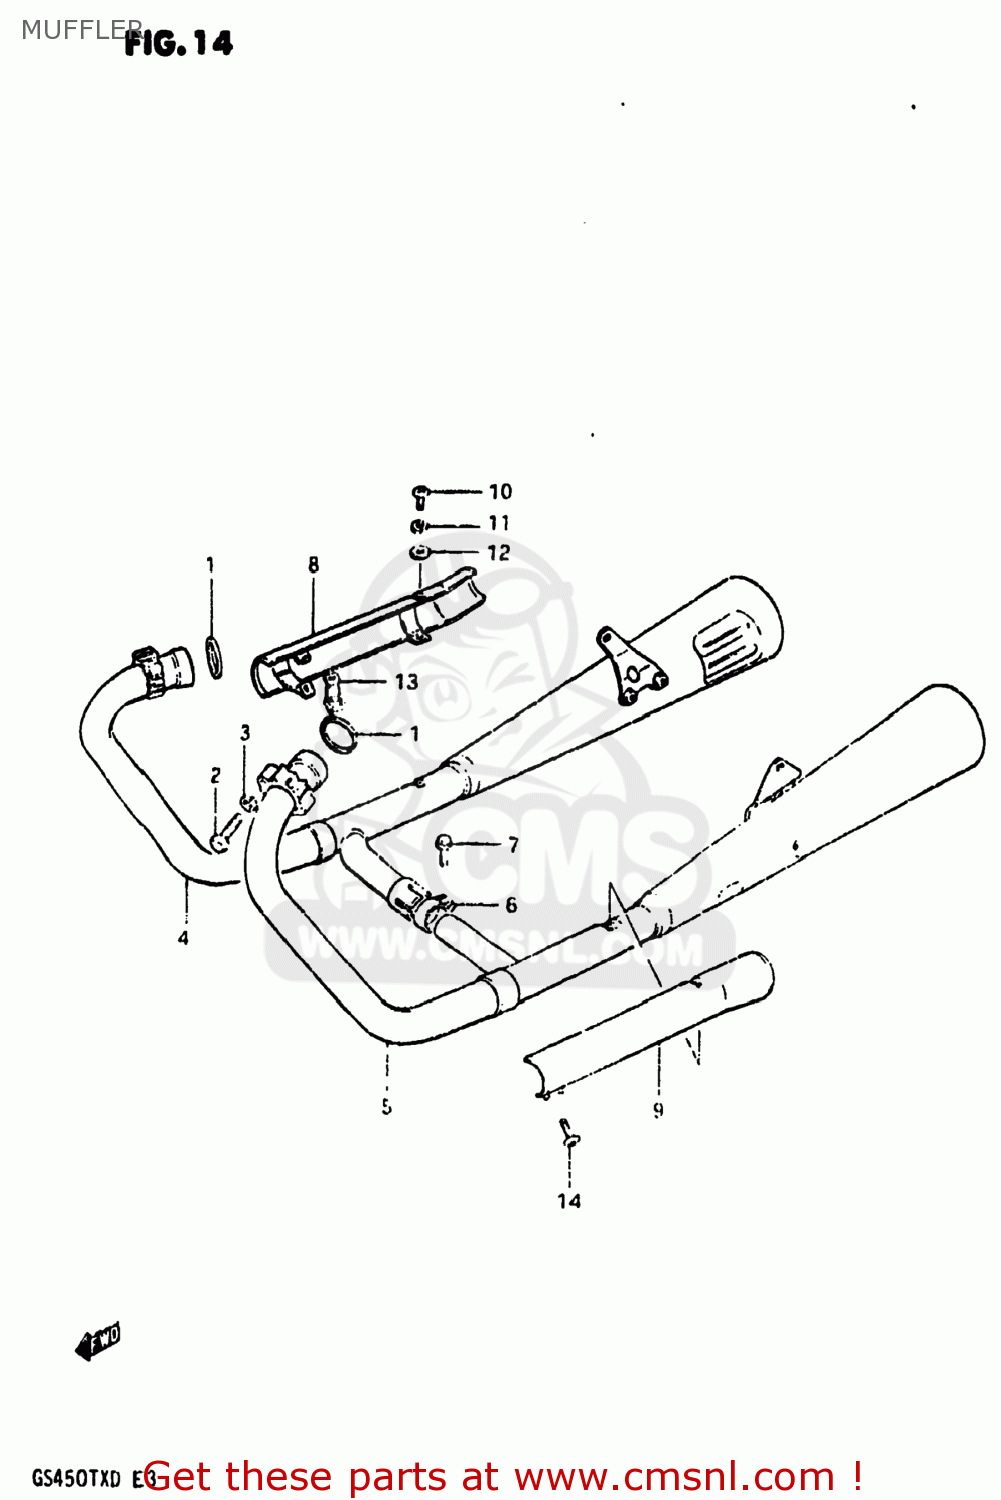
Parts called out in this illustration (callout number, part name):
1	GASKET,EXHAUST PIPE (NAS)
2	BOLT 8X40
3	LOCK WASHER
4	MUFFLER ASSEMBLY
5	MUFFLER ASSEMBLY
6	CLAMP
7	BOLT
8	COVER,MUFFLER,RIGHT
9	COVER,MUFFLER LH
10	SCREW
11	LOCK WASHER
12	WASHER
13	CLAMP,MUFFLER COVER
14	SCREW
